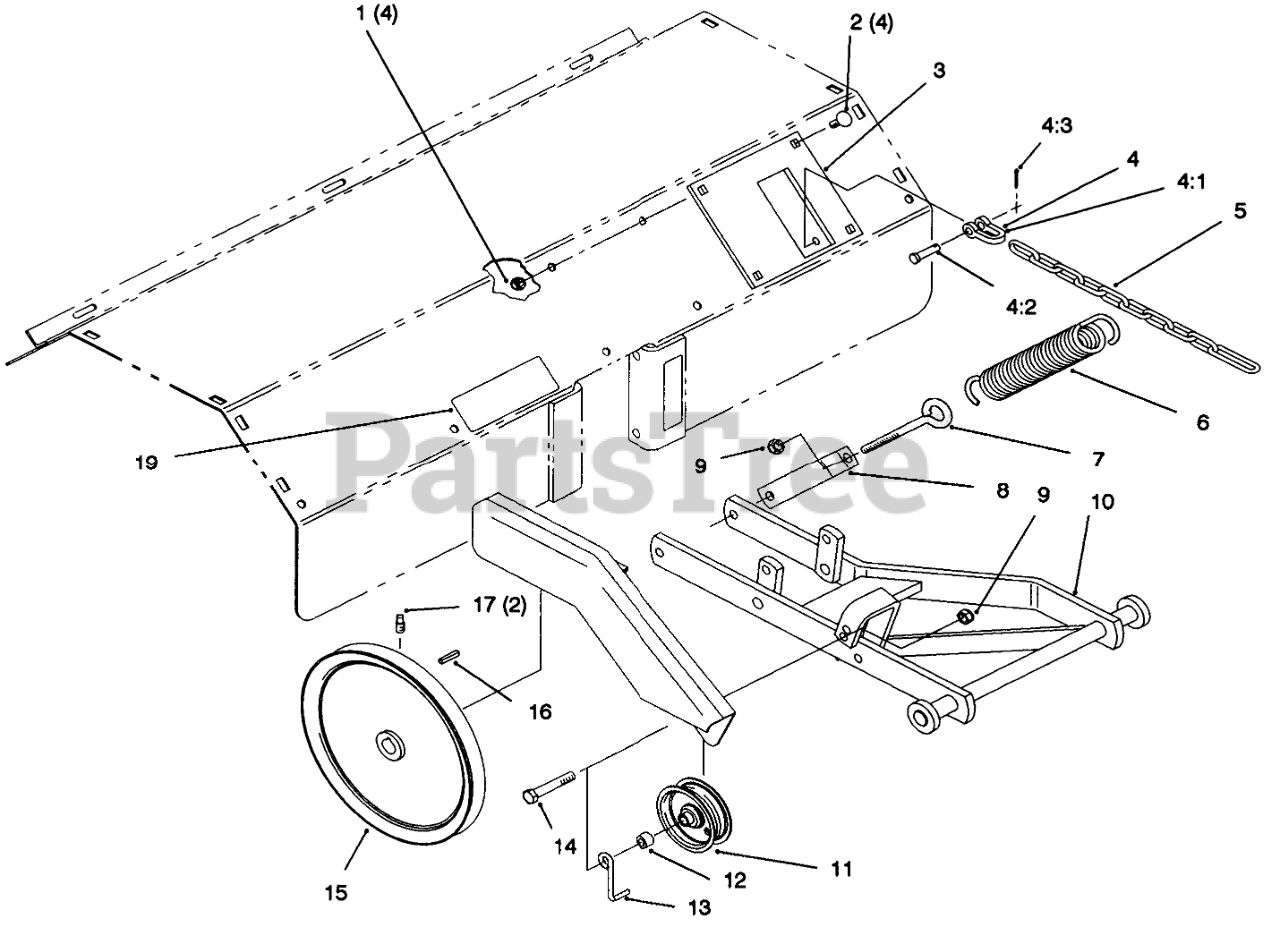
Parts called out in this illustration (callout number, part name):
1	NUT-LOCK, NI
2	BOLT-CARR
3	HITCH ASM
4	Clevis Pins Assembly (Incl. Ref .4:1, 4:2, 4:3)
4:1	Clevis
4:2	Pin-Clevis
4:3	Pin-Cotter
5	CHAIN-LIFT
6	SPRING
7	EYEBOLT
8	BRACKET - SPRING RED
9	NUT-LOCK, NI
10	Hitch
11	PULLEY-IDLER
12	Spacer
13	GUIDE-BELT
14	SCREW-HH
15	PULLEY
16	KEY-STRAIGHT
17	SCREW-SQH
19	DECAL-BELT ROUTING
